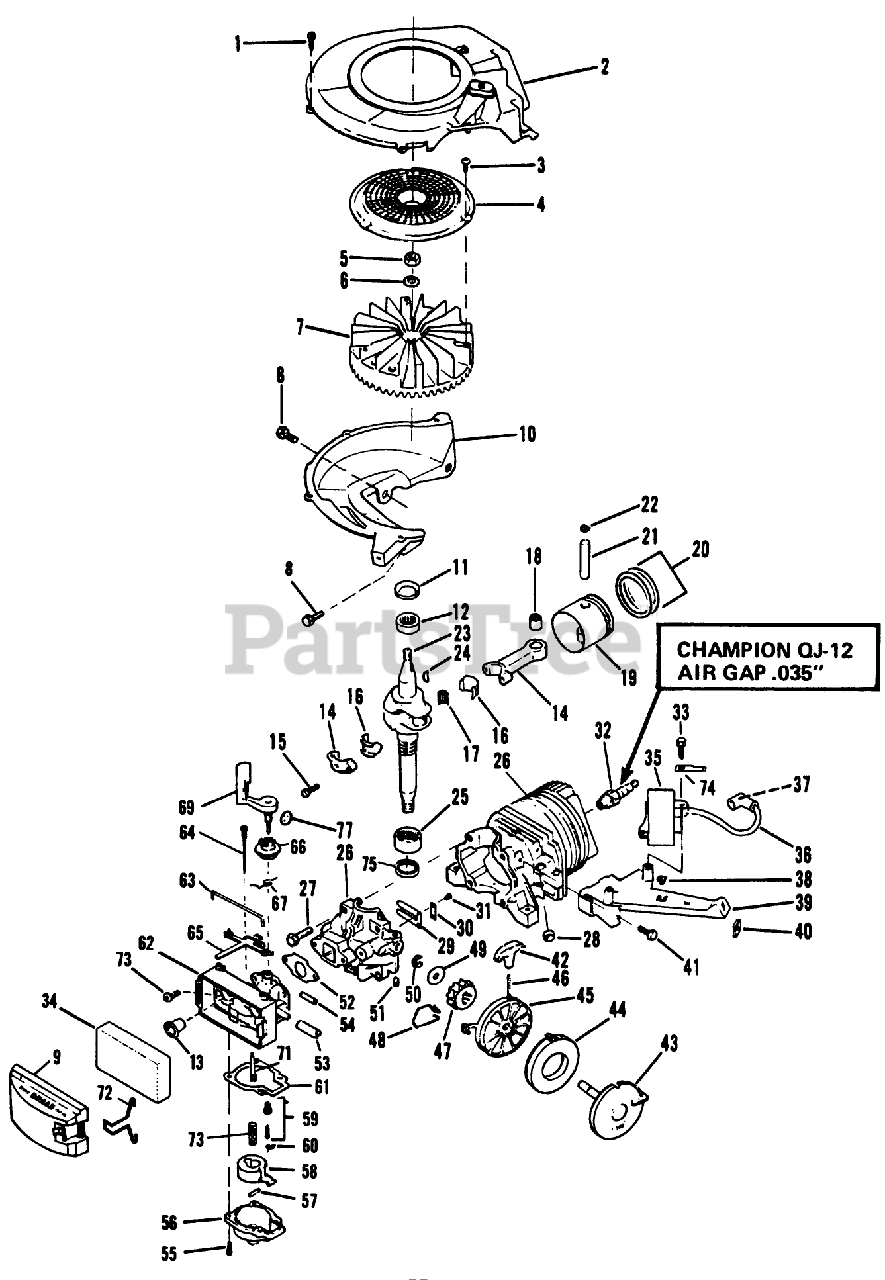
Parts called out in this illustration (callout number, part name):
1	SCREW S
2	AIR BAF&EYELET S
3	SCREW F
5	NUT
8	SCREW-SEMS
10	SHROUD BASE S
12	BEARING V
15	SCREW-HSH
16	LINER ASM
18	BEARING AY F
22	RING-RETAINING
24	KEY
25	BEARING V
27	SCREW S
28	PLUG-CORE VF
30	PLATE-BACKUP, REED
36	HT LEAD&COVER XEV
38	NUT-CLIP
40	NUT - SPEED S
42	HANDLE STARTER S
45	PULLEY STARTER S
48	SPRING F
49	WASHER S
52	GASKET CARB S
54	TUBING PRIMER S
55	SCREW-HH
62	CARB BODY S
63	RETAINER
64	NEEDLE ADJ. AY S
65	LEVER S
66	COLLAR-ADJUST, AIRVANE
67	SPRING,THROTTLE S
68	DISC S
69	AIR VANE&SHAFT S
70	FILTER-FUEL VS
72	RETAINER-COVER, FILTER
73	SCREW
74	TERMINAL S
75	SEAL-OIL
